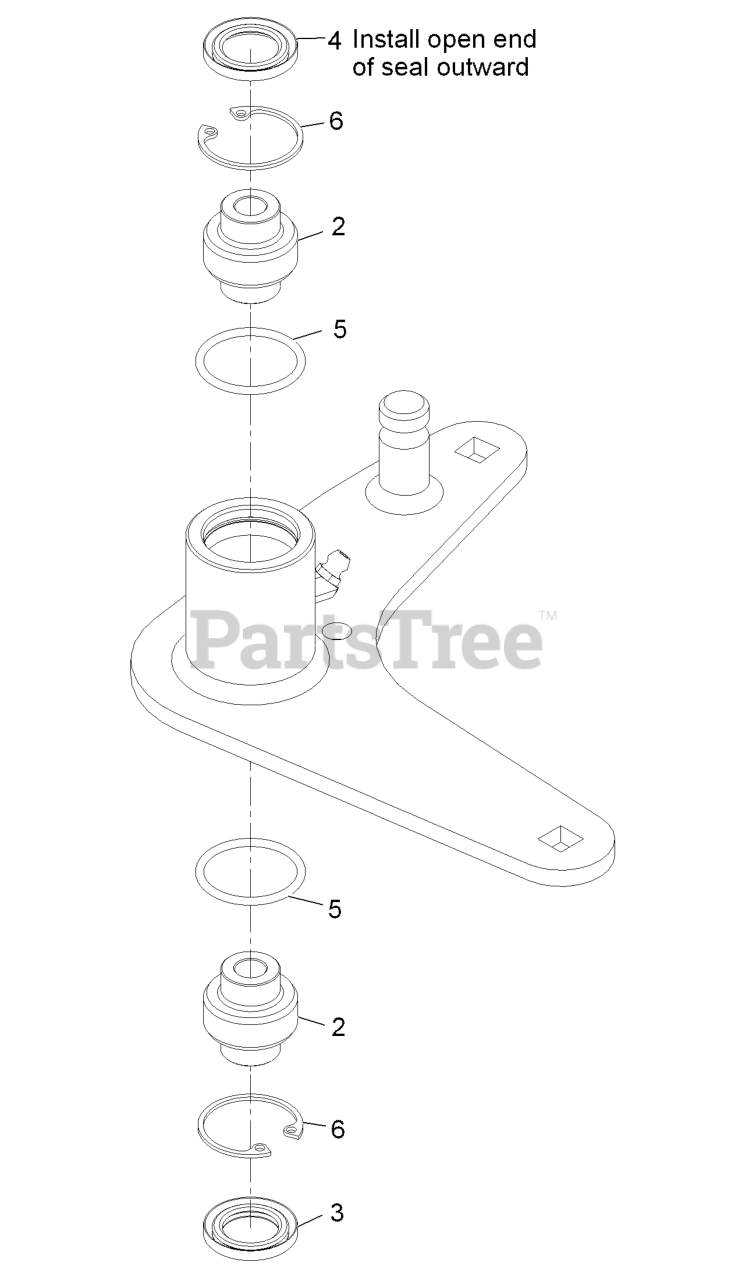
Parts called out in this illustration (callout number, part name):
2	Bearing-Spherical
3	Seal-Lip, Double
4	Seal-Single Lip
6	Ring-Retaining
